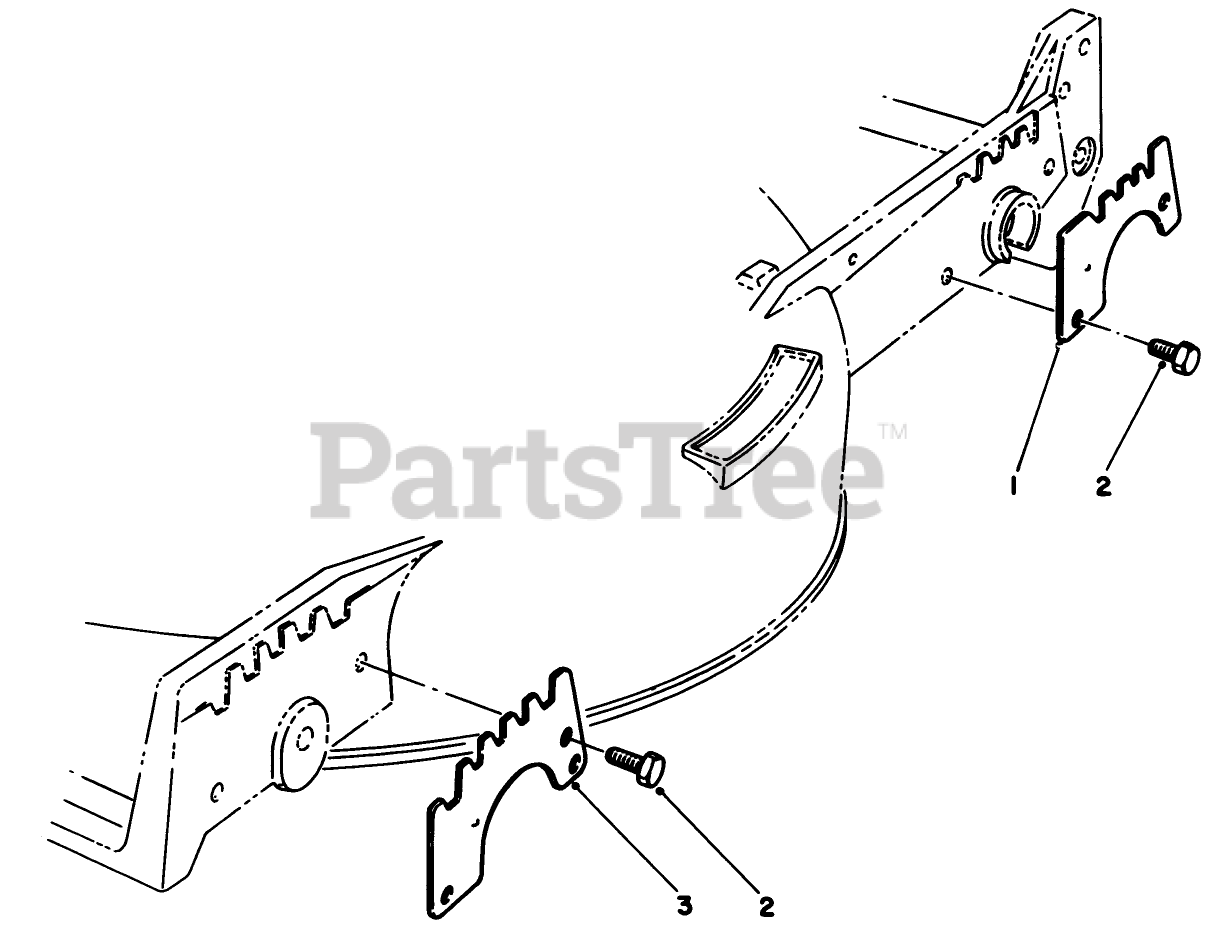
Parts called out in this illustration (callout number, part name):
1	WEAR PLATE,REAR
2	SCREW-HWH
3	WEAR PLATE
